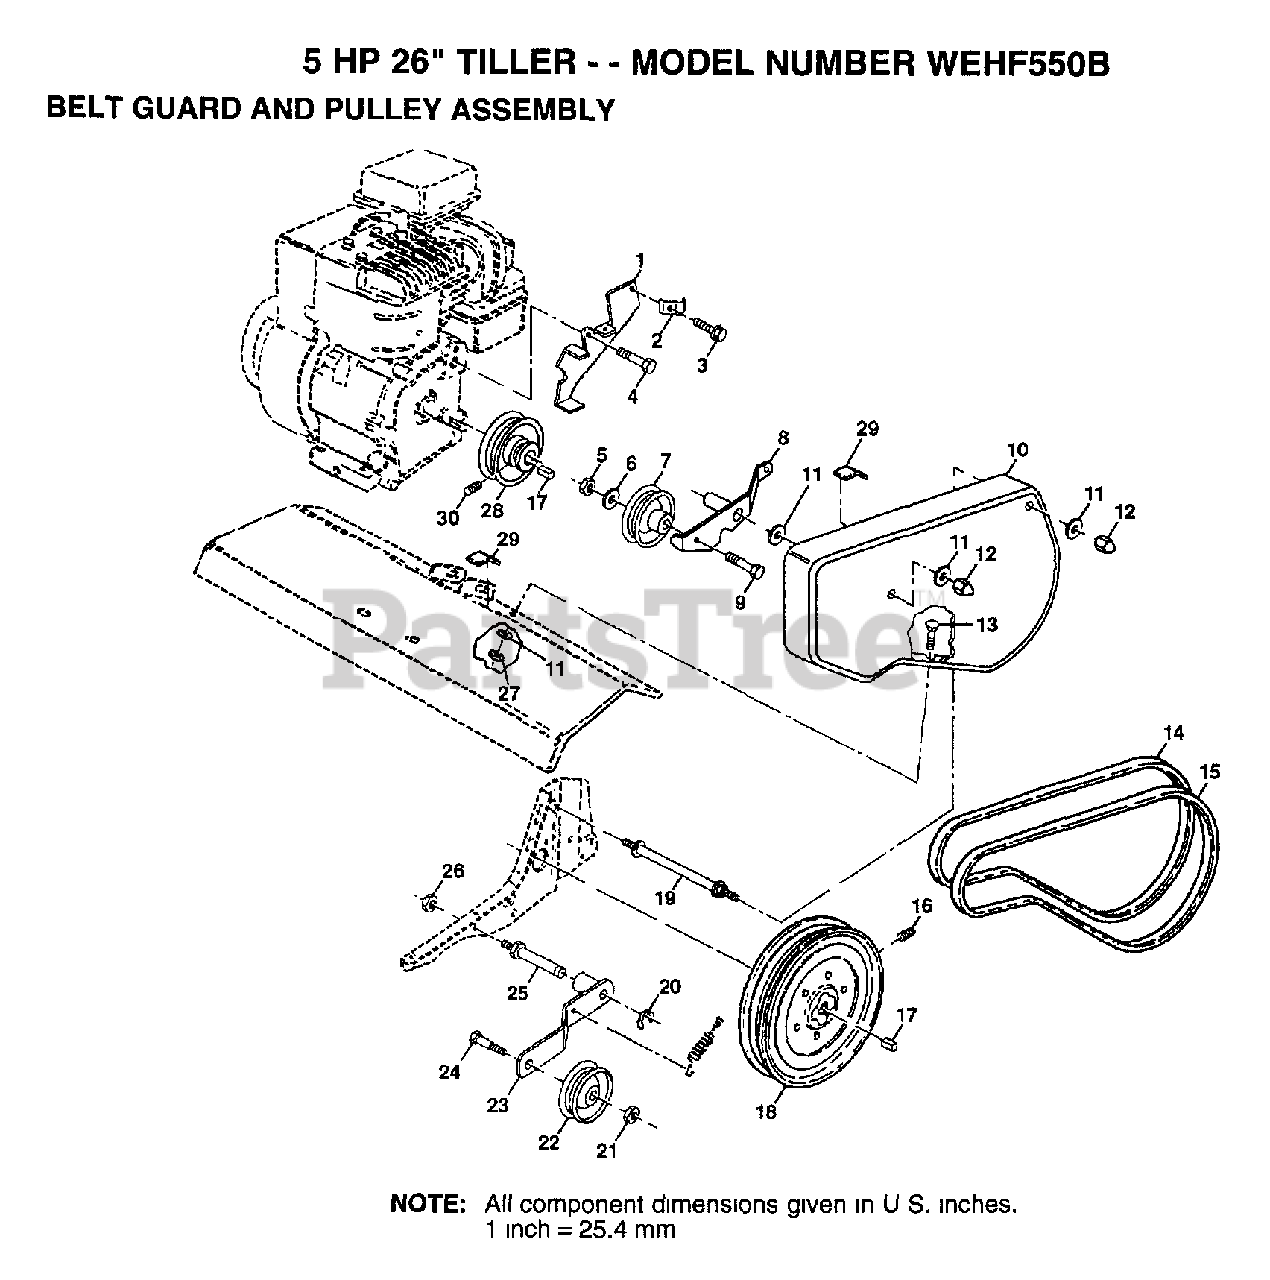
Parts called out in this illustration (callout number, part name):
2	CONDIUT CLIP T
5	NUT.HEX.3/8-16UNC
6	WASHER
7	PULLEY W/SPACER
8	ARM.ASM.REV.IDLER
11	WASHER
12	NUT-CAP TI
13	BOLT T
14	BELT-V
16	SET SCREW
17	KEY T
19	BOLT TI
20	KLIP RING TI
21	NUT
23	IDLER ARM TI
25	SHAFT IDLER TI
26	JAM NUT TI
27	NUT
28	ENGINE PULLEY TI
29	PAD IDLER TI
30	SET SCREW
